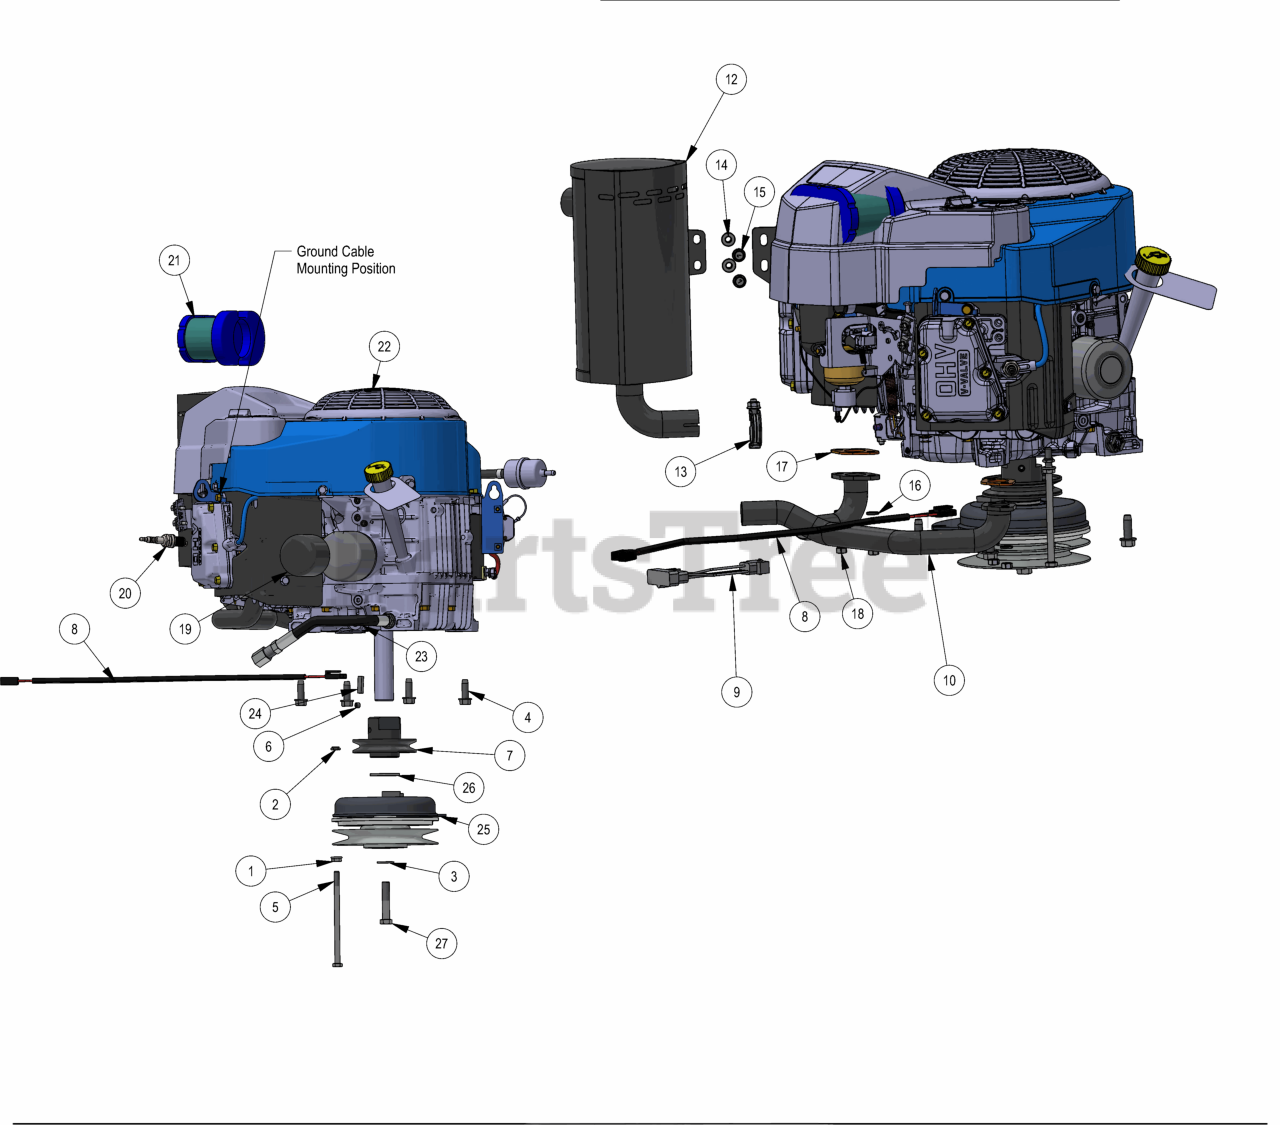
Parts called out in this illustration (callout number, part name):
1	5/16-18 HEX SERRATED FLANGE NUT HARD/ZINC
2	5/16-18 Nylock Jam Nut
3	3/8 FLAT WASHER USS (1" OD) ZINC
4	3/8-16 X 1-1/8 HEX WASHER UNSLOT SERRATED (TRI-LOB) TRS ZINC YELLOW
5	5/16-18 X 5-1/2 HEX CAP SCREW (GR.5) ZINC
6	5/16 Set Screw
7	3-3/4" Motor Pulley SD
8	Clutch Pigtail
9	2019 Harness Adaptor-Gen2 FX-ALL
10	Exhaust Pipe
11	Exhaust Bracket
13	Exhaust Clamp
14	Exhaust Nut
15	Exhaust Flange Bolt
16	Exhaust Lock Washer
17	Exhaust Gasket
18	M8-1.25 Zinc Nut
19	Oil Filter
20	Spark Plug - Kawasaki
21	Kawasaki Air Filter
22	Kawasaki 18.5HP FS600 Electric Start
23	Oil drain Hose
24	1/4 X 1 SQ MACHINERY KEY 1018 STL PLN
26	1.140 ID X 1.750 OD X .132 THICK FLAT WASHER PLAIN
27	7/16-20 X 2-1/4 HEX CAP SCREW (GR.8) With Patch
